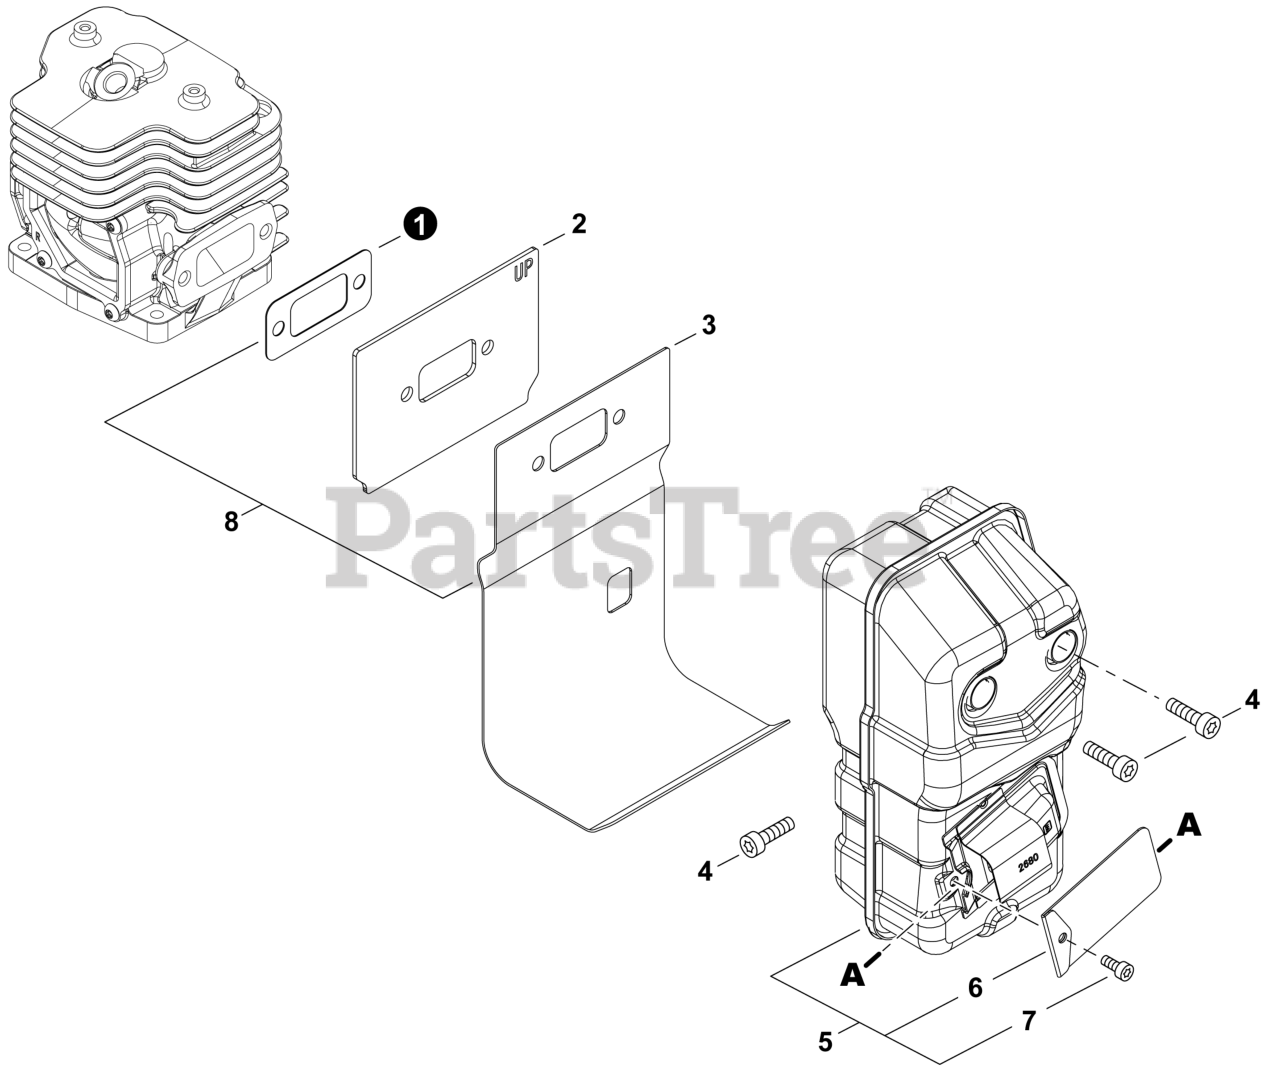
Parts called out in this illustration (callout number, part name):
1	GASKET, EXHAUST
2	PLATE, EXHAUST
3	HEAT SHIELD, EXHAUST
4	BOLT, TORX 6x20
5	MUFFLER ASSY
6	SCREEN, SPARK ARRESTER
7	BOLT, TORX 4x8
8	GASKET KIT: ENGINE, INTAKE, EXHAUST
